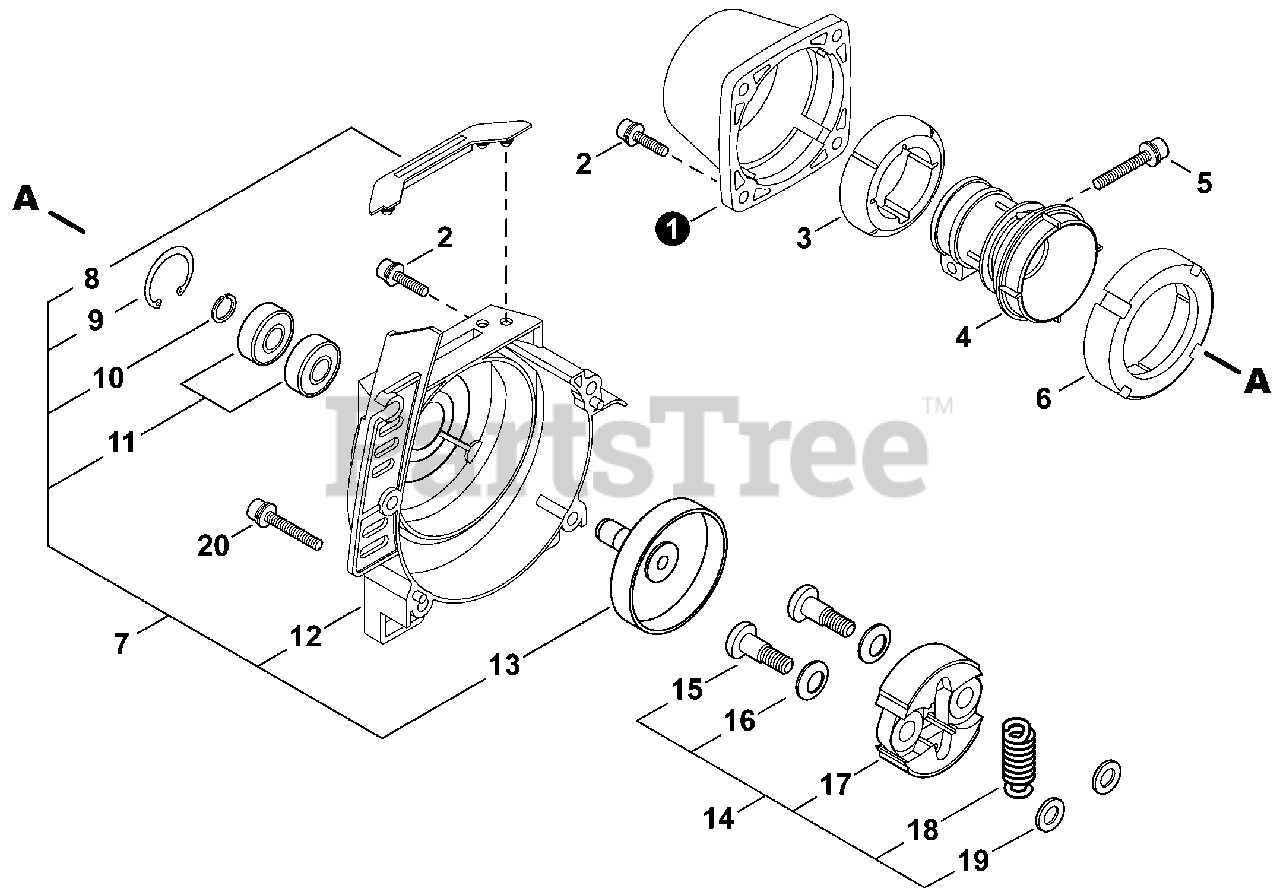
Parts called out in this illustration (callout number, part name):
1	COVER, AV CUSHION (RED)
2	BOLT 5x16
3	CUSHION, FRONT
4	CUSHION, AV
5	BOLT M5x25
6	HOLDER, REAR CUSHION
7	COVER ASSY, FAN
8	CUSHION
9	RING, SNAP ?26
10	RING, SNAP 10
11	BEARING, BALL 6000ZZ
12	COVER, FAN
13	DRUM, CLUTCH
14	CLUTCH ASSY
15	BOLT, CLUTCH
16	WASHER, SPRING
17	SHOE, CLUTCH
18	SPRING, CLUTCH
19	WASHER 6 MM
20	BOLT M5x45
